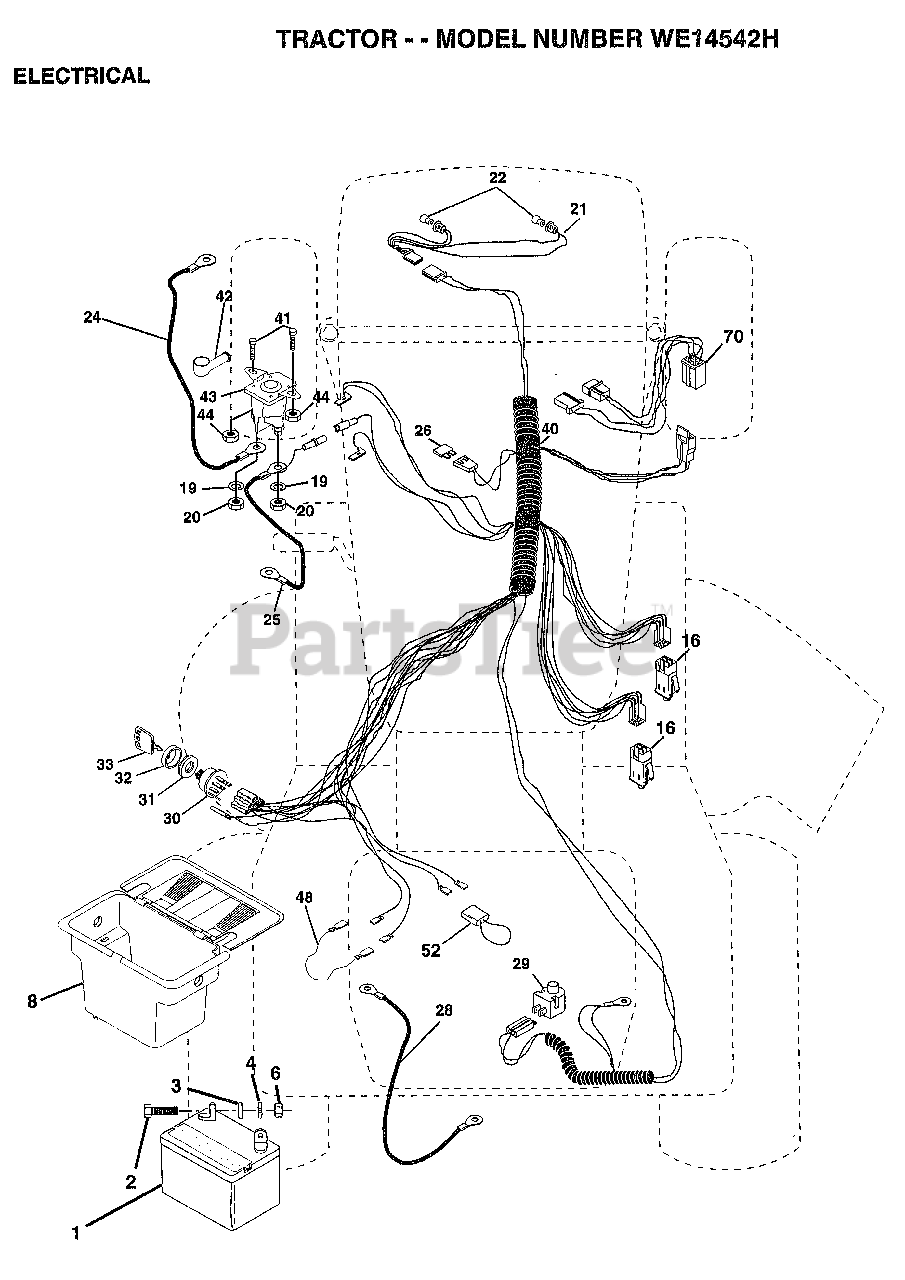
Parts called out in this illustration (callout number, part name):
3	WASHER
4	LOCKWASHER
8	"CASE,BATTERY.MECH"
16	SWITCH INTERLOCK
20	NUT
21	"HARNESS,LIGHT SOC"
22	HEADLAMP BULB
24	"CABLE T, BATTERY"
25	CABLE.BTRY.6GA.RD
26	FUSE HYT
28	CABLE T
29	SWITCH SEAT
30	SWITCH IGN 4POS
31	NUT IGNITION
32	COVER KEY SWITCH
33	KEY
40	HARNESS-IGNITION
41	BOLT HXHD FIN
44	NUT HXKEP 1/4X20
48	ADAPTER AMMETER
52	PROTECTION LOOP
70	HARNESS.ENG.DUAL
